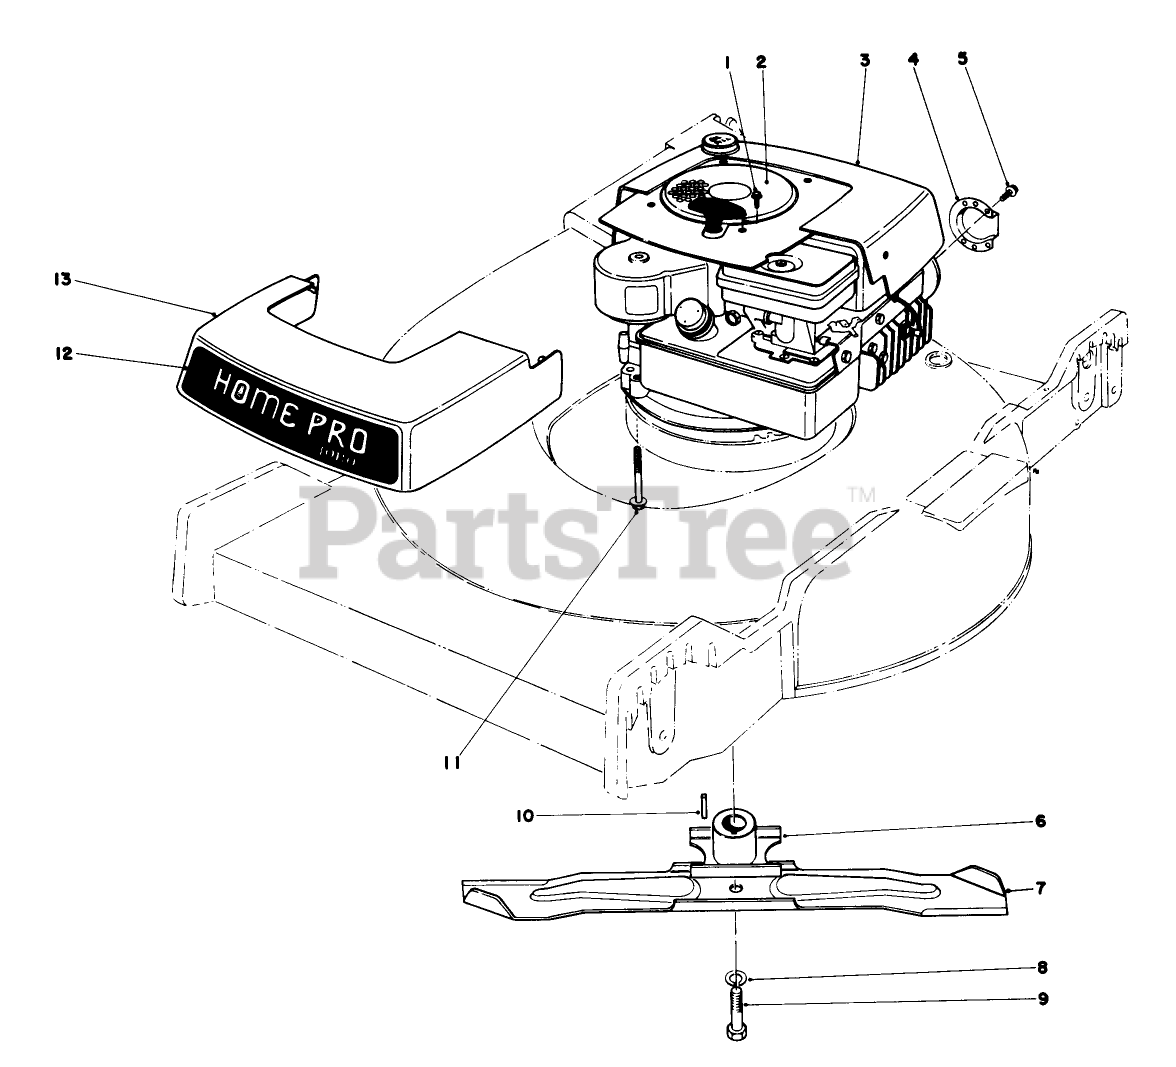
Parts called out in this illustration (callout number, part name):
1	8X1/2 SELF TAP SCREW
2	Engine
3	Shroud Rear
4	Deflector
5	SCREW W/ENGINE
6	BLADE RETAINER WA(BLACK)
7	Blade
8	WASHER-LOCK
9	BLADE SCREW
10	KEY-SQUARE
11	3/8-16 X 2-3/4 CAPSCR
12	Decal Shroud
13	Shroud Front
